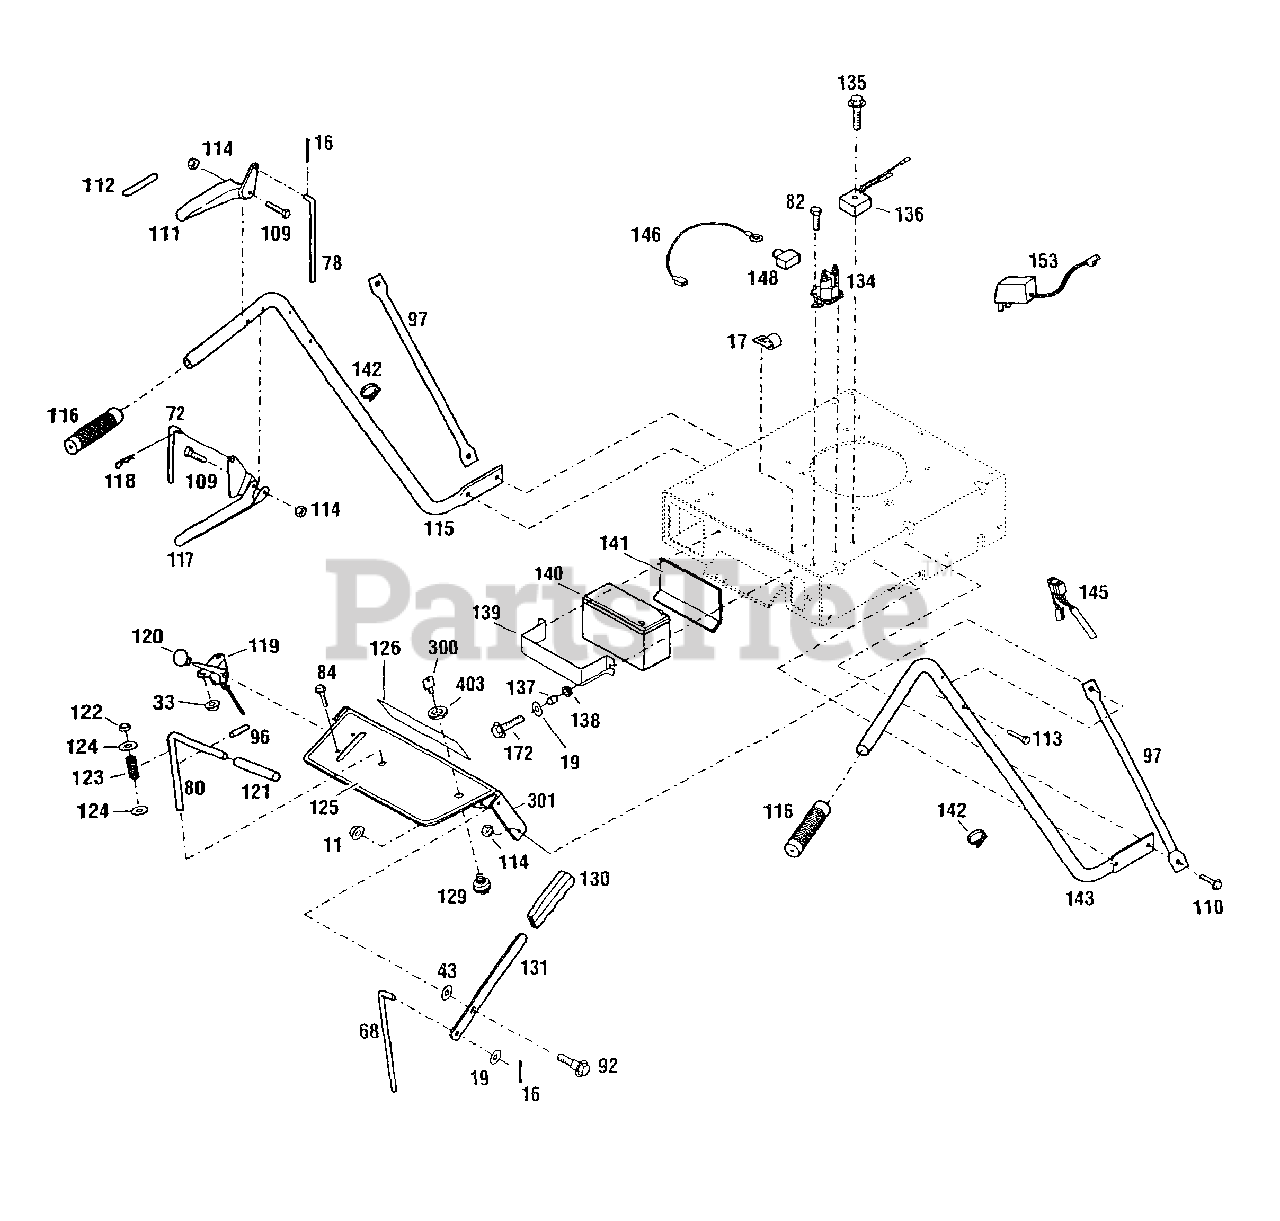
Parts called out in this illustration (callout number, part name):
11	Flange Locknut, 3/8-16
16	Cotter Pin, 3/32 x 5/8
19	Flat Washer, 5/16
33	Flange Locknut, 1/4-20
43	Flat Washer, 1/2
68	Upper Blade Rod
72	Upper Transmission Rod
78	Upper Brake Rod
80	Shift Rod
82	Thread Cut. Screw, 1/4-20 x 1/2
84	Flange Lock Screw, 1/4-20 x 1/2
92	Shoulder Bolt
96	Roll Pin, 1/4 x 2-1/4
97	Brace, Handlebar
109	Hex Screw, 1/4-20 x 1-3/4
110	Flange Lock Screw, 5/16 x 3/4
111	Control Handle
112	Operator Presence Control Decal
113	Hex Screw, 1/4-20 x 1-3/4, Grade 8
114	Locknut, 1/4-20
115	Left Handlebar
116	Handle Grip
117	Control Handle
118	Hair Pin, 5/64
119	Throttle Control
120	Knob
121	Handle Grip
122	Nylon Bushing
123	Compression Spring
124	Flat Washer, 1/2
125	Warning Decal
126	Logo Decal
129	Ignition Switch
130	Handle Grip
131	Mower Engage Lever
134	Solenoid
135	Thread-Cut. Screw, 1/4-20 x 1-1/2
136	Regulator
137	Spacer
138	Grommet
139	Battery Bracket
140	Battery
141	Battery Pad
142	Plastic Tie
143	Right Handlebar
145	Wiring Harness
146	Wire Lead
148	Boot
153	Battery Charger
172	Screw, 5/16-18 x 3/4"
300	Ignition Key
301	Console Assembly
403	Nut, Ignition Switch
